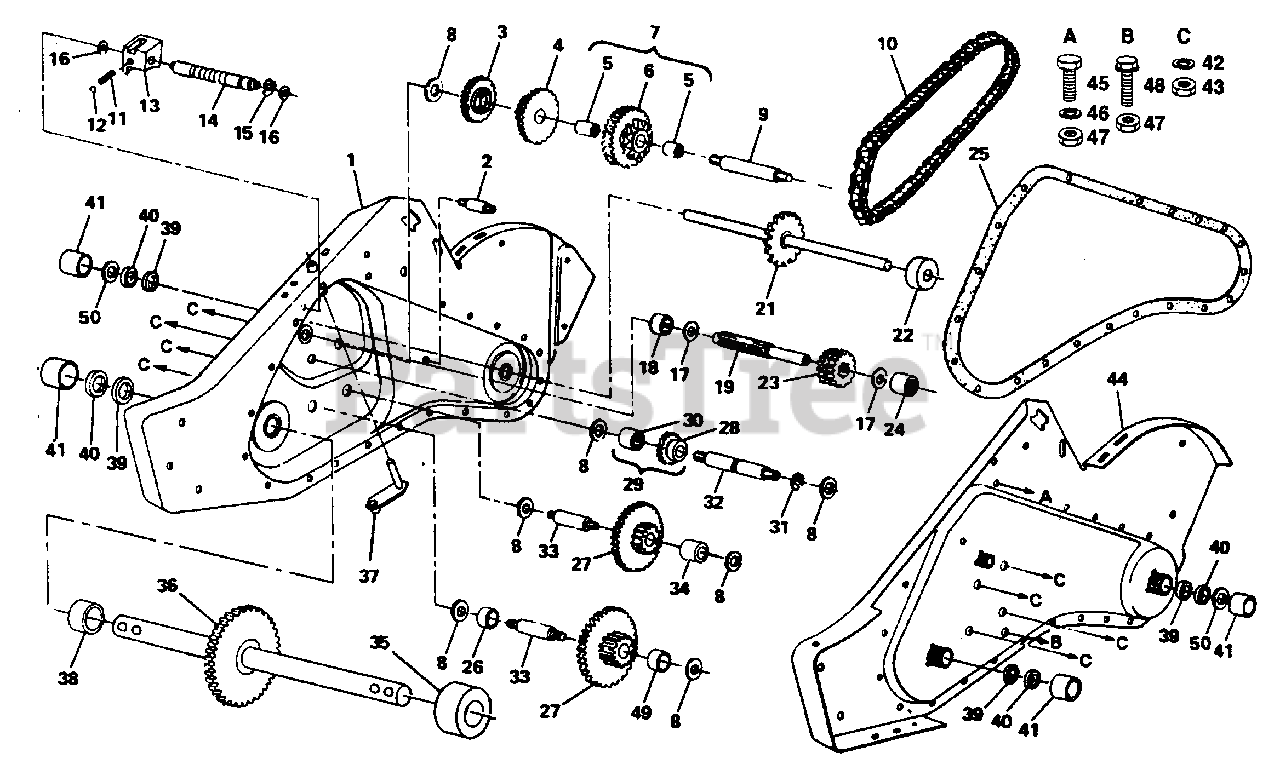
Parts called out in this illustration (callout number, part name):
1	Gearcase Assembly, R.H., with Bearing (Includes Key No. 18) (AYP part number)
2	Bolt, Upset (AYP part number)
3	Gear, Reverse (AYP part number)
4	Gear, Cluster, Red., 1st and 2nd (AYP part number)
5	Bearing, Needle (AYP part number)
6	Sprocket Assembly, Tine (AYP part number)
7	Sprocket Assembly with Bearings (Includes Key #6 & two of Key #5) (AYP part number)
8	Washer (AYP part number)
9	Shaft, Reduction, 1st (AYP part number)
10	Chain, Roller, 60P (AYP part number)
11	Spring, Shift, Fork (AYP part number)
12	Ball, Steel (AYP part number)
13	Fork, Shift
14	Shaft, Shift (AYP part number)
15	Klip Ring (AYP part number)
16	Washer, Seal (AYP part number)
17	Race, Bearing, Thrust, 5/8 I.D. (AYP part number)
18	Bearing, Needle (AYP part number)
19	Shaft, Input (AYP part number)
21	Shaft Assembly, Tine (AYP part number)
22	Spacer 1.008 x 1-3/4 x .645 (AYP part number)
23	Pinion, Input (AYP part number)
24	Bearing, Needle (AYP part number)
25	Gasket, Gearcase (AYP part number)
26	Spacer .765 I.D. x 1.12 x 5/8 (AYP part number)
27	Gear, Cluster, Red., 2nd and 3rd (AYP part number)
28	Gear, Reverse Idler (AYP part number)
29	Gear Assembly, Reverse Idler (Includes Key Numbers 28 and 30) (AYP part number)
30	Bearing, Needle (AYP part number)
31	Klip Ring (AYP part number)
32	Shaft, Reverse Idler (AYP part number)
33	Shaft, Reduction, 2nd (AYP part number)
34	Spacer .765 I.D. x 1-1/8 x 1-3/8 (AYP part number)
35	Spacer, Ground Drive, L.H. (AYP part number)
36	Shaft Assembly, Ground (AYP part number)
37	Arm Assembly, Shift
38	Spacer, Ground Drive, R.H. (AYP part number)
39	Seal, Oil (AYP part number)
40	Seal, Ring, Rubber (AYP part number)
41	Cup, Formed (AYP part number)
42	Washer, Lock 7/16 (AYP part number)
43	Nut, Hex 7/16-20 (AYP part number)
44	Gearcase Assembly, L.H., with Bearing (Includes Key Number 24) (AYP part number)
45	Bolt, Hex Head 5/16-18 x 3/4 (AYP part number)
46	Washer, Lock 5/16 (AYP part number)
47	Nut, Hex Head 5/16-18 (AYP part number)
48	Screw, Whiz-Lock 5/16-18 x 4 (AYP part number)
49	Spacer .765 I.D. x 1.12 x 3/4 (AYP part number)
50	Ring, Spiral (AYP part number)
